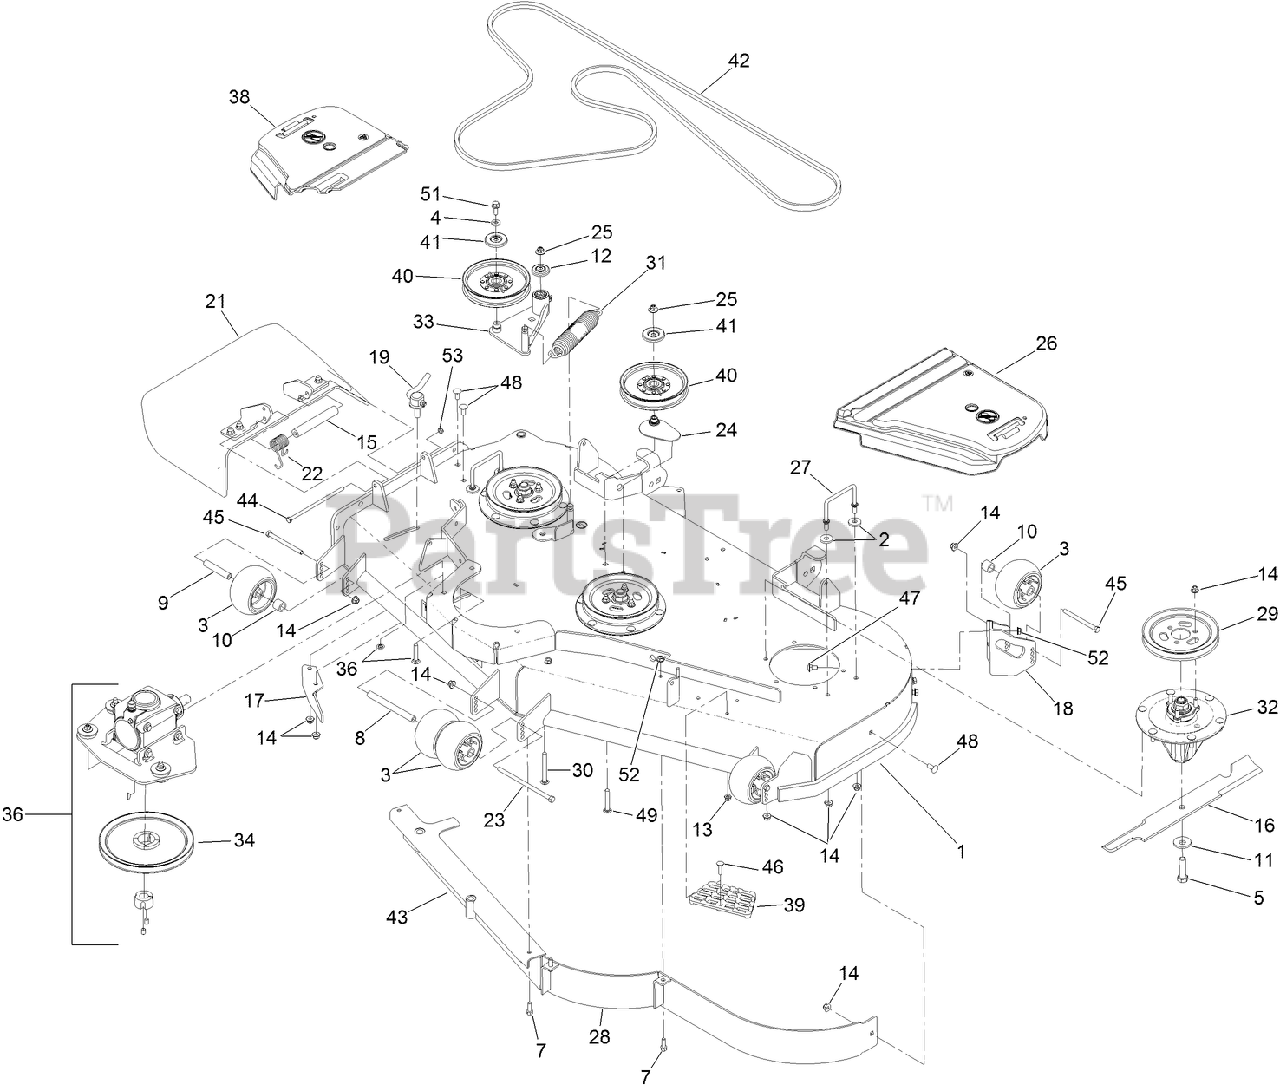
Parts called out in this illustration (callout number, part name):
1	DECK DECAL ASM
2	WASHER
3	ROLLER-SCALP, ANTI
4	SPACER
5	SCREW-BLADE
8	SPACER-WHEEL
9	TUBE-SPANNER
10	TUBE-SPACER
11	WASHER-BLADE BOLT, HEAVY
12	GUARD-TOP
13	NUT-HF, NI
14	NUT-HF, NI
15	SPACER
16	BLADE-HI FLOW
17	BAFFLE-DISCHARGE
18	MOUNT-WHEEL, LH
19	LEVER ASM
21	RUBBER DEFLECTOR ASM
22	SPRING-TORSION
23	SCREW-HH
24	SPACER-PULLEY
25	NUT-FLANGE, NI
26	COVER-BELT, LH
27	WIREFORM-COVER
29	PULLEY
30	BOLT-SHOULDER, CARRIAGE
31	SPRING-EXTENSION
32	SPINDLE ASM
33	IDLER ARM ASM
34	PULLEY
36	GEARBOX ASM
38	BELTSHIELD-RT, 60
39	STEP-DECK
40	IDLER-PULLEY
41	SHIELD-DUST
42	BELT-V, B
43	BAFFLE ASM
44	SCREW-HH
45	SCREW-HH
46	SCREW-CARR
47	SCREW-HH
48	SCREW-CARR
49	SCREW-CARR
51	SCREW-HHF
52	NUT-HHF, WHIZ
53	NUT-LOCK, NI
